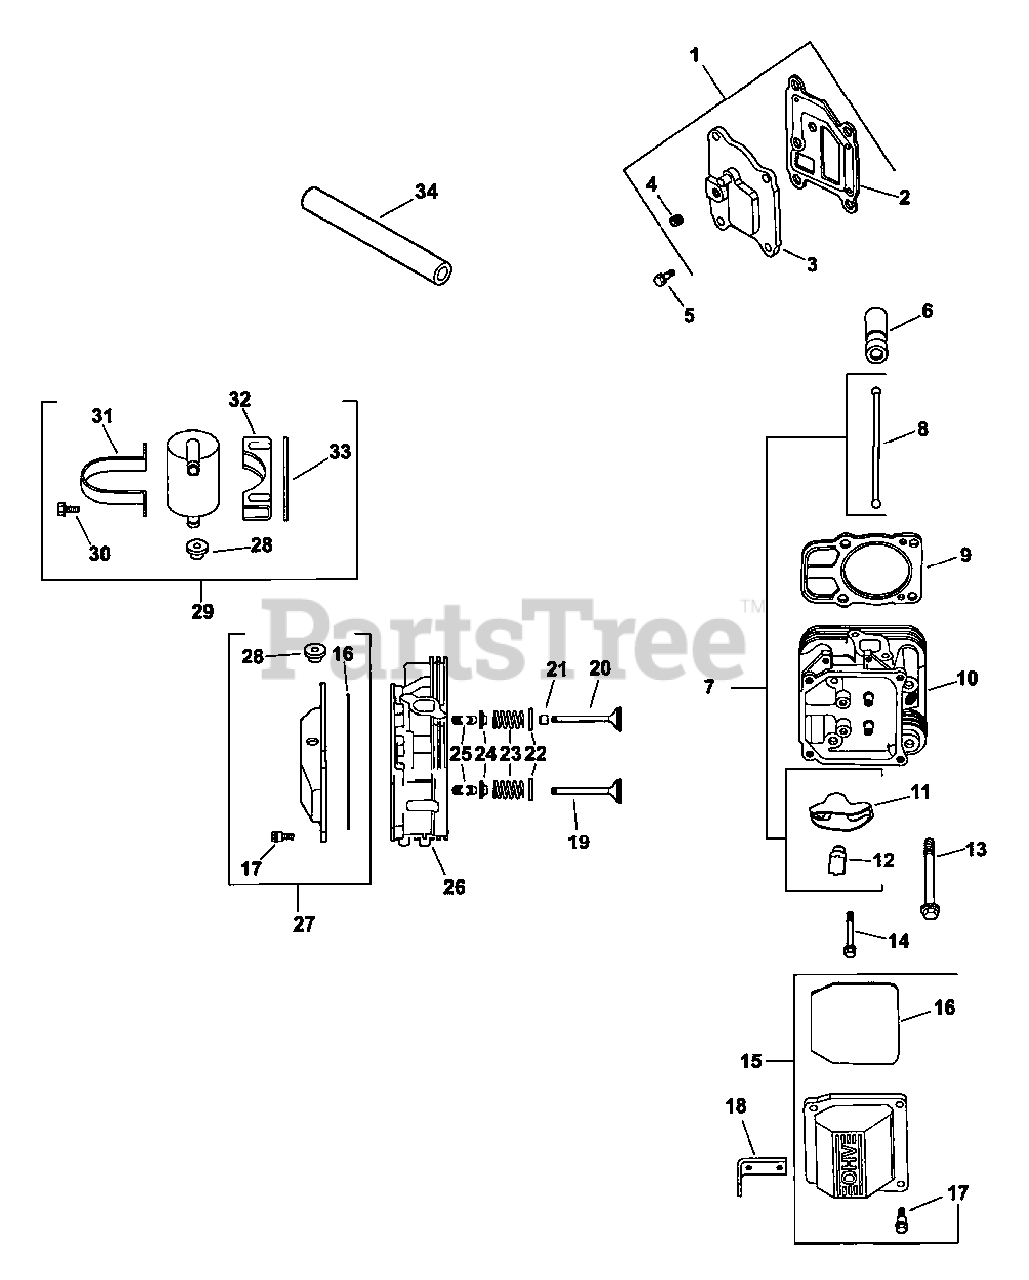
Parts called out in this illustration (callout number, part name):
1	Breather Cover w/Gasket Kit
2	Breather Gasket
3	Breather Cover
4	Plug, Pipe 1/8"
5	Hex Flange Screw (M6 x 1.0 x 20)
6	Valve Lifter
7	Valve Train Kit
9	Cylinder Head Gasket
10	Head Assembly # 2 Cylinder
12	Rocker Arm Pivot
13	Screw, Hex Flange
14	Hex Flange Screw (M6 x 1.0 x 34)
15	Valve Cover Kit
17	Screw, Shoulder (M6 x 1.0 x 30)
18	Lifting Strap
19	Exhaust Valve (Std.)
20	Intake Valve (Std.)
21	Valve Stem Seal
22	Spring Retainer
23	Valve Spring
24	Valve Spring Cap
25	Retainer Kit
26	Head Assembly # 1 Cylinder
27	Breather Valve Cover Kit
28	Rubber Grommet
29	Breather Seperator Kit
30	Hex Flange Screw (M5 x .8 x 16)
31	Breather Strap
32	Breather Seperator Bracket
34	Breather Hose
